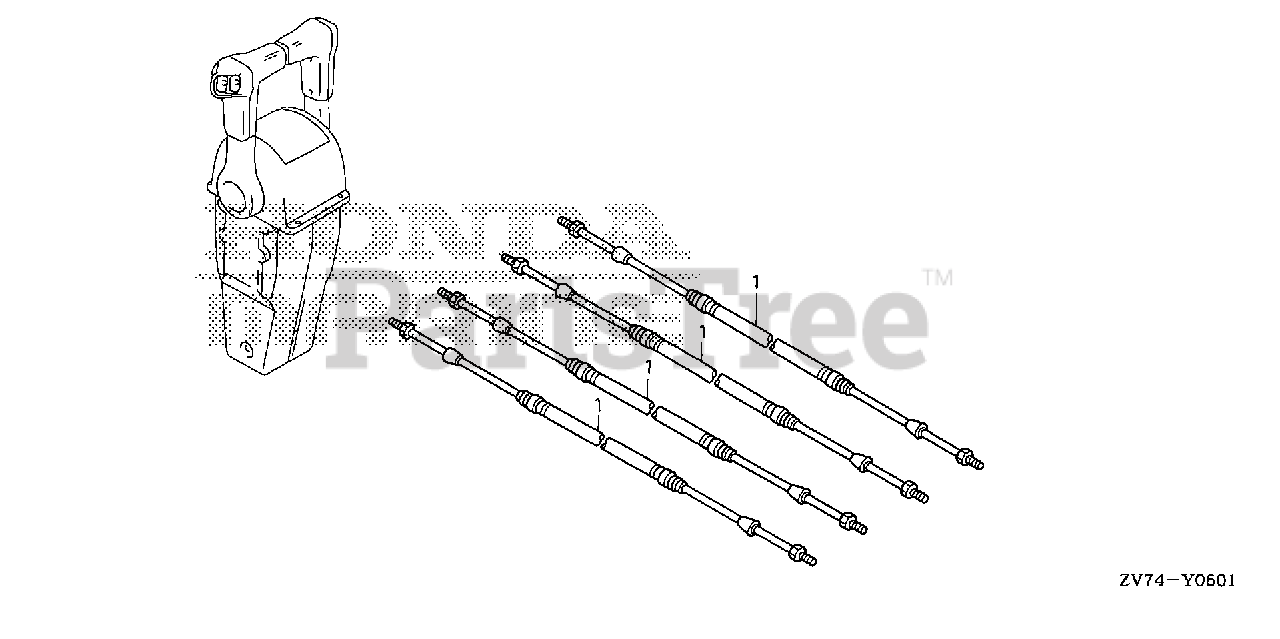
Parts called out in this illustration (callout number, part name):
1	CABLE ASSY., PUSH-PULL (33C-5FT)
1	CABLE ASSY., PUSH-PULL (33C-6FT)
1	CABLE ASSY., PUSH-PULL (33C-7FT)
1	CABLE ASSY., PUSH-PULL (33C-8FT)
1	CABLE ASSY., PUSH-PULL (33C-9FT)
1	CABLE ASSY., PUSH-PULL (33C-10FT)
1	CABLE ASSY., PUSH-PULL (33C-11FT)
1	CABLE ASSY., PUSH-PULL (33C-12FT)
1	CABLE ASSY., PUSH-PULL (33C-13FT)
1	CABLE ASSY., PUSH-PULL (33C-14FT)
1	CABLE ASSY., PUSH-PULL (33C-15FT)
1	CABLE ASSY., PUSH-PULL (33C-16FT)
1	CABLE ASSY., PUSH-PULL (33C-17FT)
1	CABLE ASSY., PUSH-PULL (33C-18FT)
1	CABLE ASSY., PUSH-PULL (33C-19FT)
1	CABLE ASSY., PUSH-PULL (33C-20FT)
1	CABLE ASSY., PUSH-PULL (33C-21FT)
1	CABLE ASSY., PUSH-PULL (33C-22FT)
1	CABLE ASSY., PUSH-PULL (33C-23FT)
1	CABLE ASSY., PUSH-PULL (33C-24FT)
1	CABLE ASSY., PUSH-PULL (33C-25FT)
1	CABLE ASSY., PUSH-PULL (33C-26FT)
1	CABLE ASSY., PUSH-PULL (33C-27FT)
1	CABLE ASSY., PUSH-PULL (33C-28FT)
1	CABLE ASSY., PUSH-PULL (33C-29FT)
1	CABLE ASSY., PUSH-PULL (33C-30FT)
1	CABLE ASSY., PUSH-PULL (33C-31FT)
1	CABLE ASSY., PUSH-PULL (33C-32FT)
